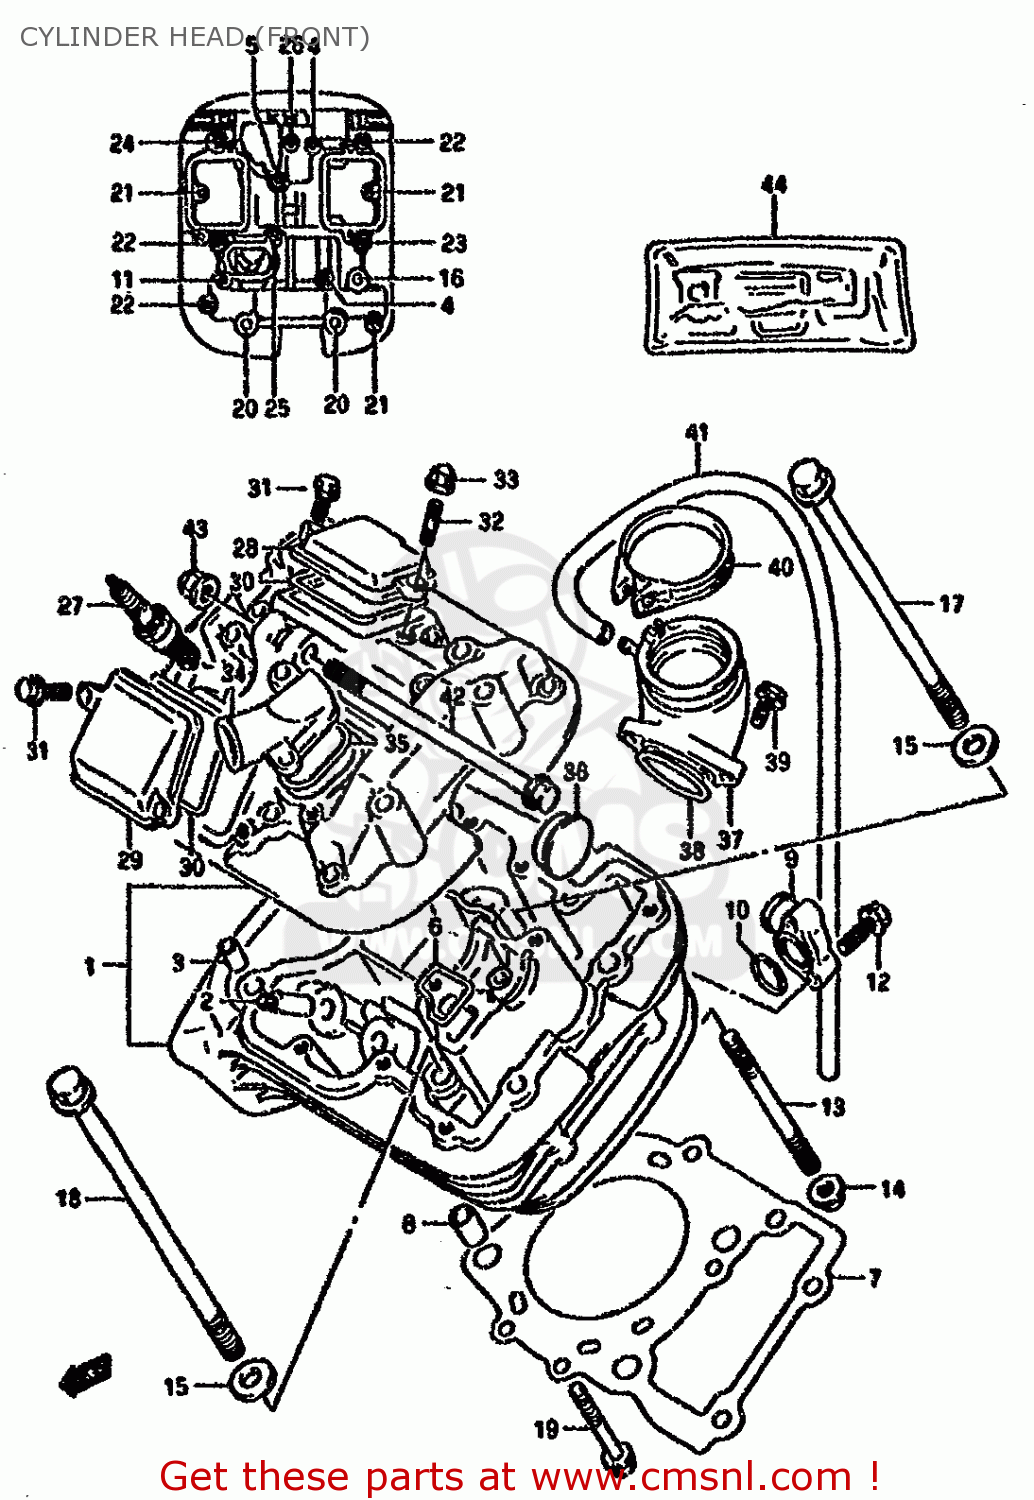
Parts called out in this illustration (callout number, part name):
1	HEAD ASSY,CYLINDER FRONT
2	GUIDE,VALVE
3	PIN(11X14)
4	BOLT(6X50)
5	BOLT(6X55)
6	GASKET,CYLINDER HEAD WATER (NAS)
7	GASKET,CYLINDER HEAD FR (NAS)
8	PIN
9	UNION,CYLINDER HEAD WATER
10	O RING(D:2.4,ID:17.8)
11	BOLT
12	BOLT
13	BOLT,STUD
14	NUT
15	WASHER(10.5X22X2.3)
16	BOLT(8X140)
17	BOLT(10X155)
18	BOLT(10X165)
19	BOLT
20	BOLT 8X235
21	BOLT
22	BOLT
23	BOLT
24	BOLT
25	BOLT(6X55)
26	BOLT(6X50)
27	PLUG,SPARK(DPR8EA-9)
28	CAP,INSP.INT
29	CAP,INSPECTION,EXHAUST
30	GASKET,INSPECTION CAP (NAS)
31	BOLT
32	STUD 6X16
33	NUT
34	UNION,WATER OUTLET
35	GASKET,WATER OUTLET UNION (NAS)
36	PLUG(OD:30)
37	PIPE,INTAKE
38	O-RING (D:2.4 ID:39.7)
39	BOLT
40	CLAMP
41	HOSE(5X9X2000)
42	BOLT,ENGINE MOUNTING (8X150)
43	NUT
44	GASKET SET
